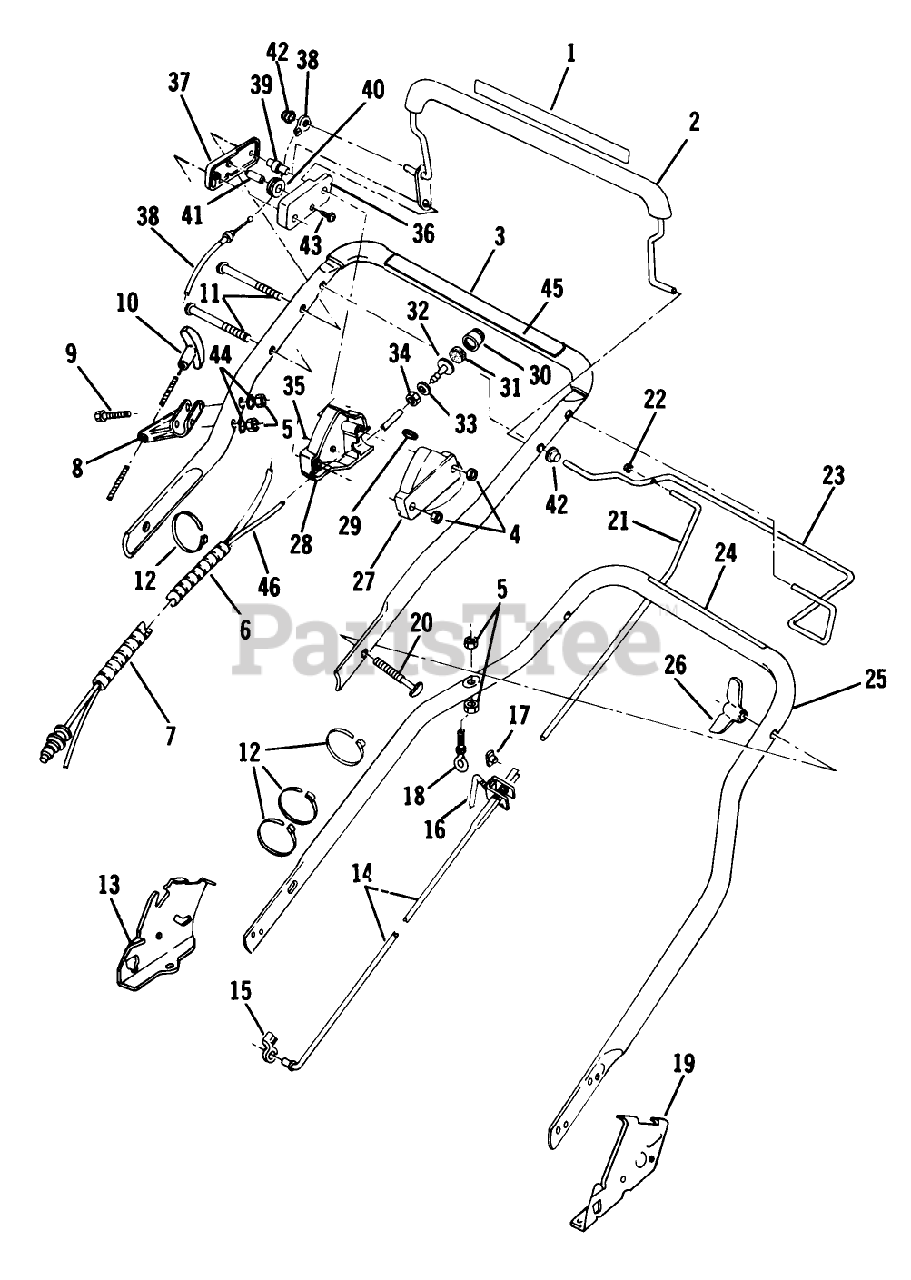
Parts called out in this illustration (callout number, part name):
4	NUT C/LOCK E
5	LOCKNUT E
10	HANDLE,STARTER
14	Control Rod Ass-y.
15	CLIP
18	EYE BOLT WAS MFG
20	BOLT QUALITY
23	LEVER
26	NUT-WING
31	FILTER S
34	LOCKNUT S
41	PIN SKF
